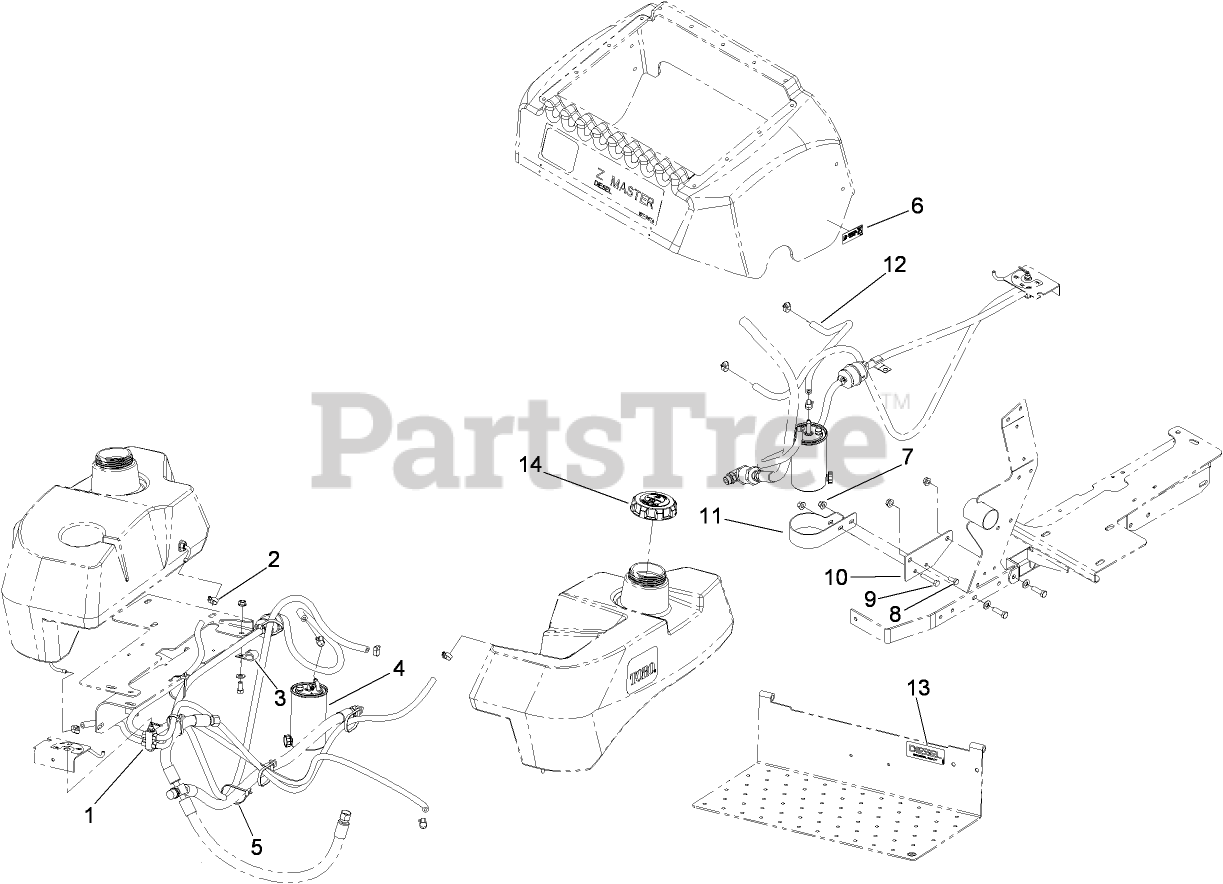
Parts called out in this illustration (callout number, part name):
1	FUEL HOSES AND FILTER ASM (Not serviced separately)
2	CLAMP-WORM
3	CLAMP-J
4	ELEMENT-FILTER, FUEL/WATER
5	TIE-PLASTIC
6	DECAL-LOW SULFUR
7	NUT-LOCK, NI
8	SCREW-HH
9	SCREW-HH
10	PLATE-FUEL FILTER MOUNT
11	BRACKET-FILTER, FUEL
12	HOSE-FUEL
13	DECAL-DIESEL, BIO-READY
14	BIODIESEL CAP ASM
